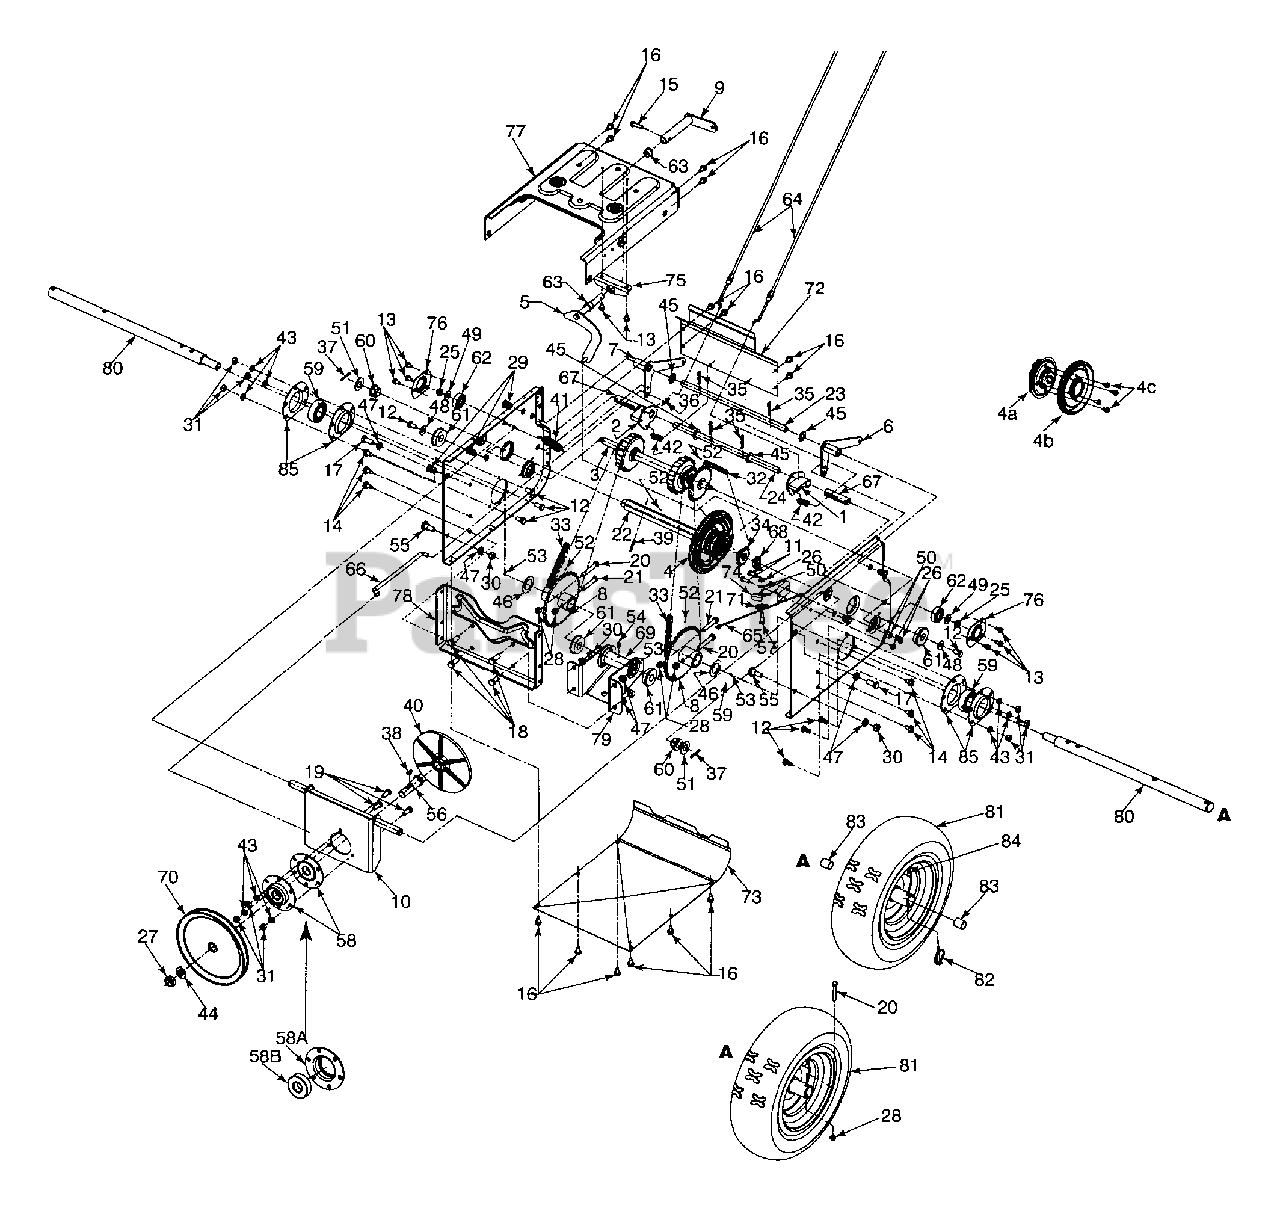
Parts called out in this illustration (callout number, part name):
1	LH Dog Assembly
2	RH Dog Assembly
3	Steering Shaft Assembly
4A	Wheel Ass'y Bearing 6.0" OD
4B	Friction Wheel Bonded
4C	Hex Wash. Hd. TT Scr. 1/4-14 x .625
5	Shift Ass'y Rod
6	Actuator Auger Bracket Ass'y
12	Hex L-Bolt 5/16-18 x .62
13	Hex Wash S-Tapp Scr 1 /4-20 x .50
14	Hex Wash Hd Tap Scr. 5/16-18 x .75
15	Hex Bolt 1 /4-20 x 1.00
16	Hex Wash Hd TT Scr. 1 /4-20 x .625
17	Hex Hd. C-Sunk Scr. 3/8-16 x.880 Gr. 5
18	Hex Hd. C-Sunk Scr. 3/8-16 x .880 Gr. 5
19	Hex Bolt 5/16-18 x .75" Lg. Gr. 5
20	Hex Hd Cap Scr. 5/16-18 x 2.0 Gr. 5
21	Hex Screw 5/16-18 x 1.75" Lg.
22	Hex Drive Shaft
23	Actuator Shaft
24	Actuator Drive Shaft
25	Hex Nut 3/8-24
26	Hex Nut 1/4-28
27	Hex Ins. Jam Locknut 5/8-18
29	Nut Insert 3/8-16 UNC
30	Hex Nut 3/8-16
31	Hex Nut 5/16-18 hd. (Gr. 5)
32	#41 Chain 1/2" pitch x 36 links- Endless
33	#420 Chain 1/2" pitch x 40 links-Endless
34	10T Sprocket #41 x .500
35	Internal Cotter Pin
36	Int. Cotter Pin 5/16 DIA
37	Cotter Pin 1/8 x 1.0
38	No. 61 Hi-Pro Key 3/16 x 5/8
39	E-ring .875 diam.
40	Aluminum Drive Plate
41	Idler Extension Spring
42	Extension Spring .47 OD x 2.03 Lg.
43	L-Wash 5/16 ID
44	Lockwasher 5/16 ID
45	Flat Washer .531 ID x .930 OD
46	Flat Washer 1.03 ID x 1.62 OD x .03
47	Lockwasher Heavy 3/8" ID
48	Cupped Washer.345 ID x .88 OD x .06
49	Flat Washer.385 ID x .87 OD x .06
50	L-Wash 1/4 ID
51	Flat Washer .64 ID x 1.24 OD x .06
52	Lubricant - LPS 2 Industrial Strength
53	Grease:Arctic:EP NLGI 1-58F
54	Grease Fitting
55	Shld. Scr. .500 Dia. x .335" Lg.
56	Drive Plate Spindle
57	Hex Shld.Scr.1/4-28 x .375
58	Ball Bearing .787 ID x 1.85 OD x .56
58A	Bearing Hsg. Ass'y.
58B	Brg. Housing 1.85" ID
59	Self aligning brg. 1.0 ID
60	Hex Flange Bearing .630 ID
61	Ball Bearing w/snap ring
62	Ball Bearing .5625 ID x 1.3750 x .437
63	Flange Bushing .500 ID x .627 OD
64	Steering Cable
65	Auger Idler Cable
66	Drive Clutch Rod
67	Split Spacer 1/2 x 5/8 x 2.69
68	Spacer.625 ID x 1.0 OD x .23
69	Spacer.6725 ID x 1.125 OD x 2.485
70	1/2" "V" Pulley.625 ID x 7.50 OD
71	Cable Guide Roller
80	Axle .995 x 14.10" Lg (30" & 33")
81	Wheel Assembly; 16 x 6.5 x 8 X-Trac (LH)
81	Wheel Assembly; 16.5 x 4.8 Snow Hog
82	Klik Pin
83	Bearing 1.0 ID x 1.127 OD x 1.00
84	Air Valve
85	Bearing Housing
86	Flange L-Nut 3/8-16 Gr. F Nylon
87	Flange L-Nut 5/16-18 Gr. F Nylon
